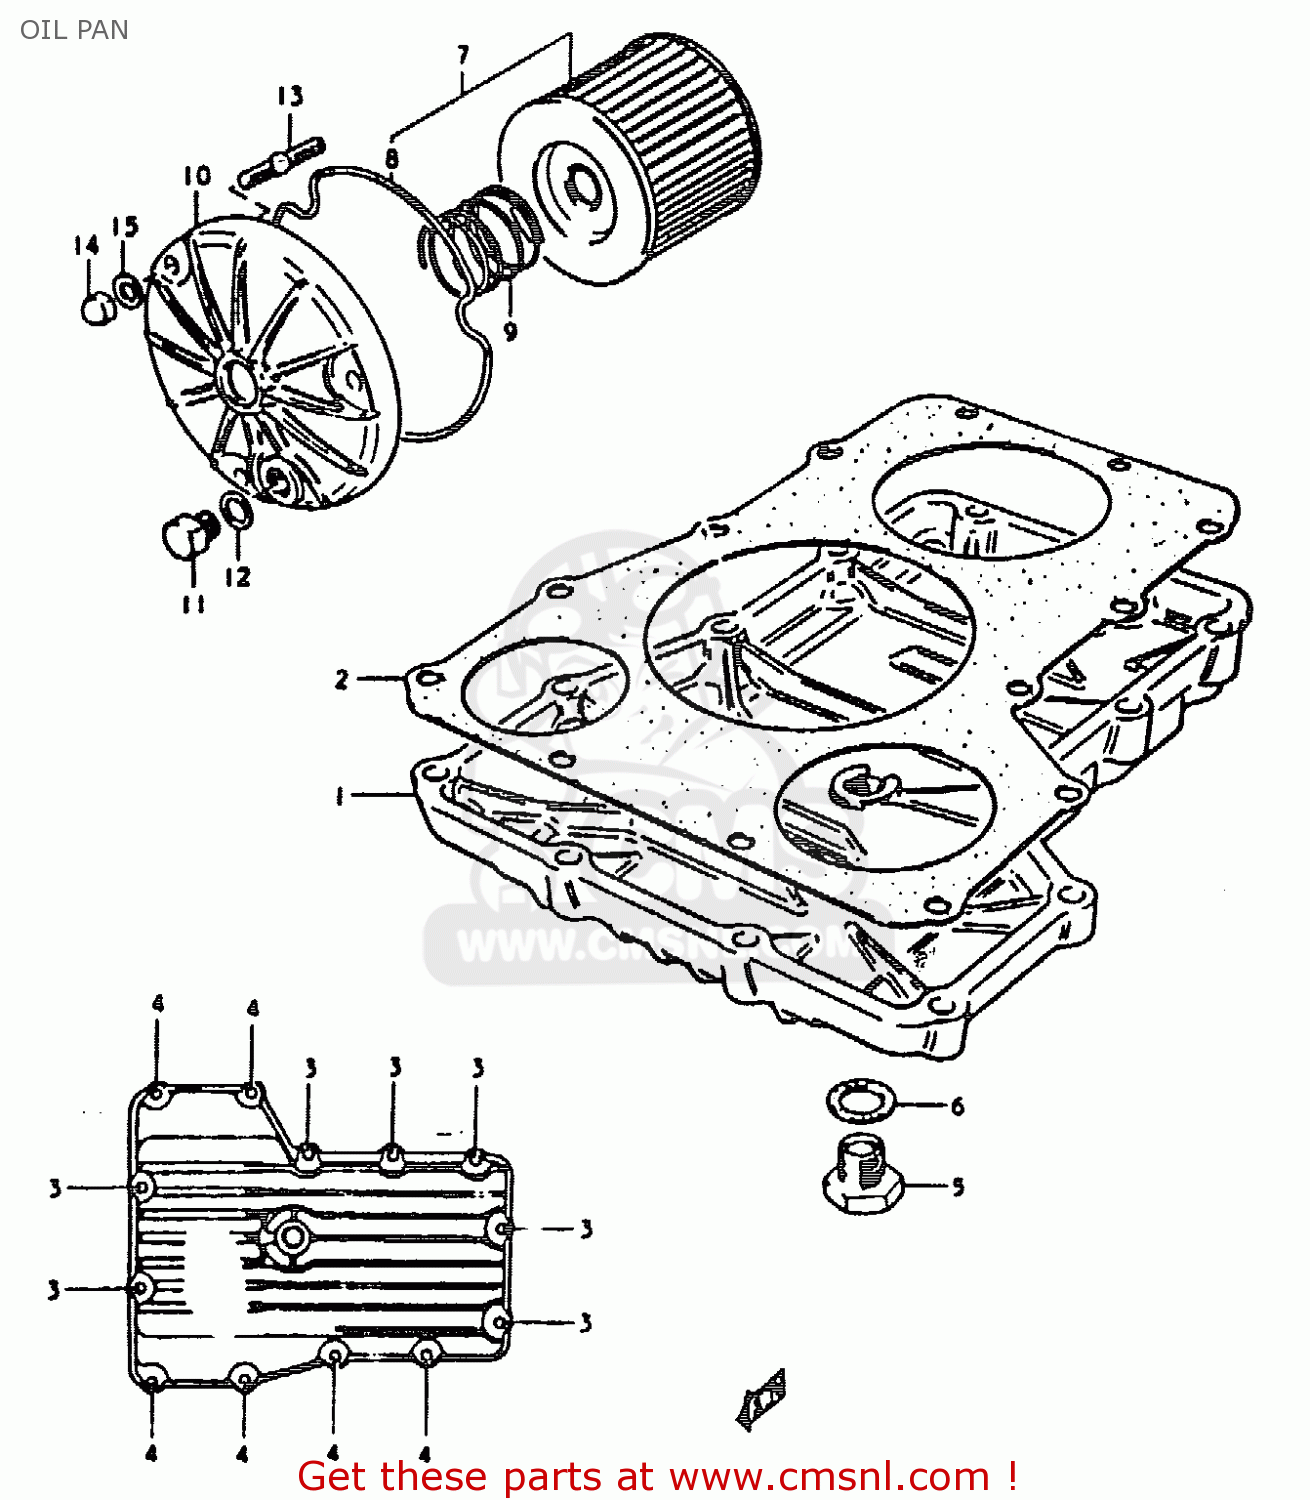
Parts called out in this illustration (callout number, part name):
1	PAN,OIL
2	GASKET,OIL PAN (MCA)
3	BOLT
4	BOLT
5	PLUG
6	GASKET(14X19.2X2) (NAS)
7	ENGINE OIL FILTER SET
8	O RING,OIL FILTER CHAMBER CAP
9	SPRING
10	CAP,OIL FILTER
11	PLUG
12	GASKET(10X14X3.6) (NAS)
13	STUD 6X20
14	NUT
15	WASHER
